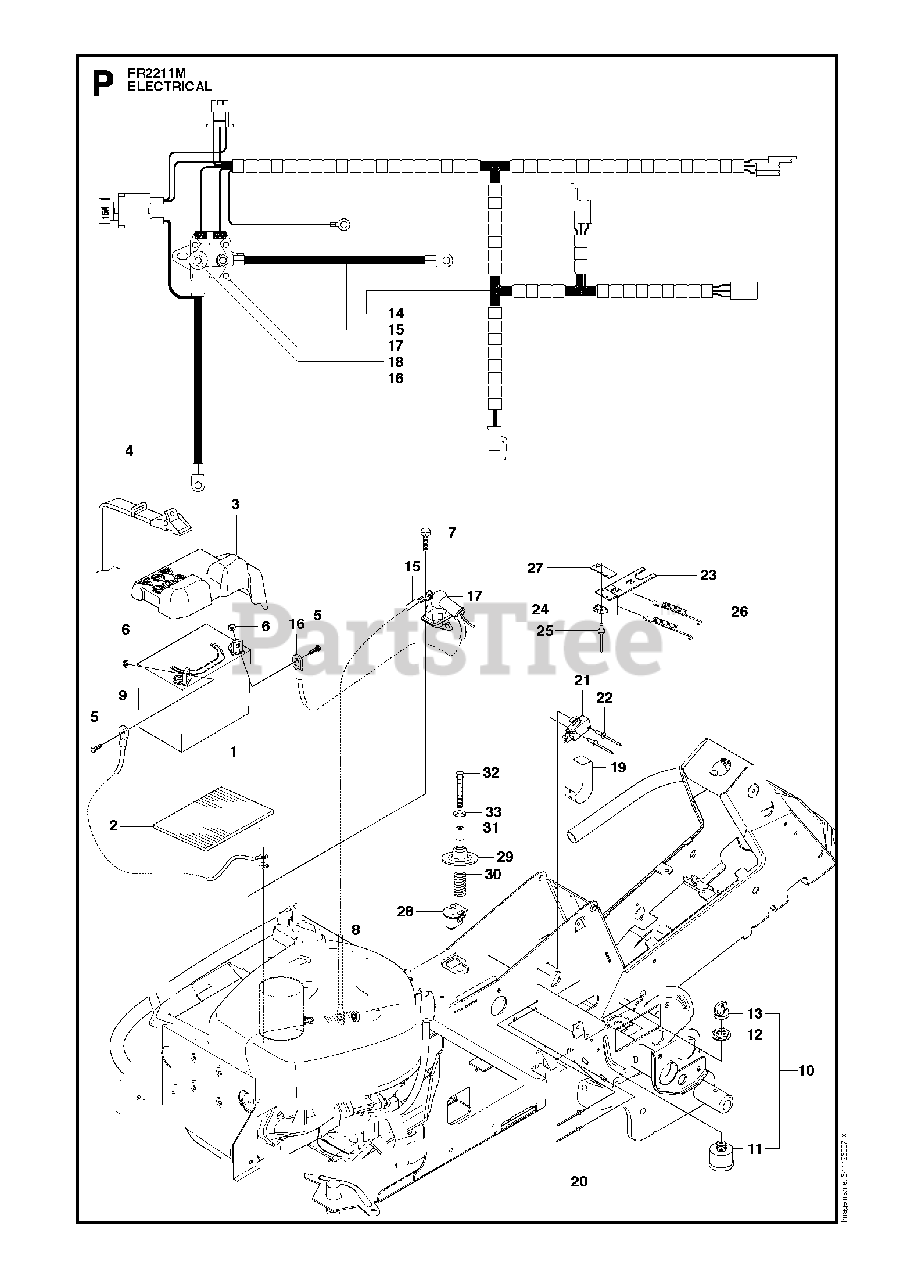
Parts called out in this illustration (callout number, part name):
5	SCREW EHHM
10	IGNITION SWITCH
11	IGNITION SWITCH
12	NUT
13	IGNITION KEY
21	%BRAKER
26	SPRING
31	SPACER TUBE
32	SCREW
33	WASHER BRB 8.4X17
